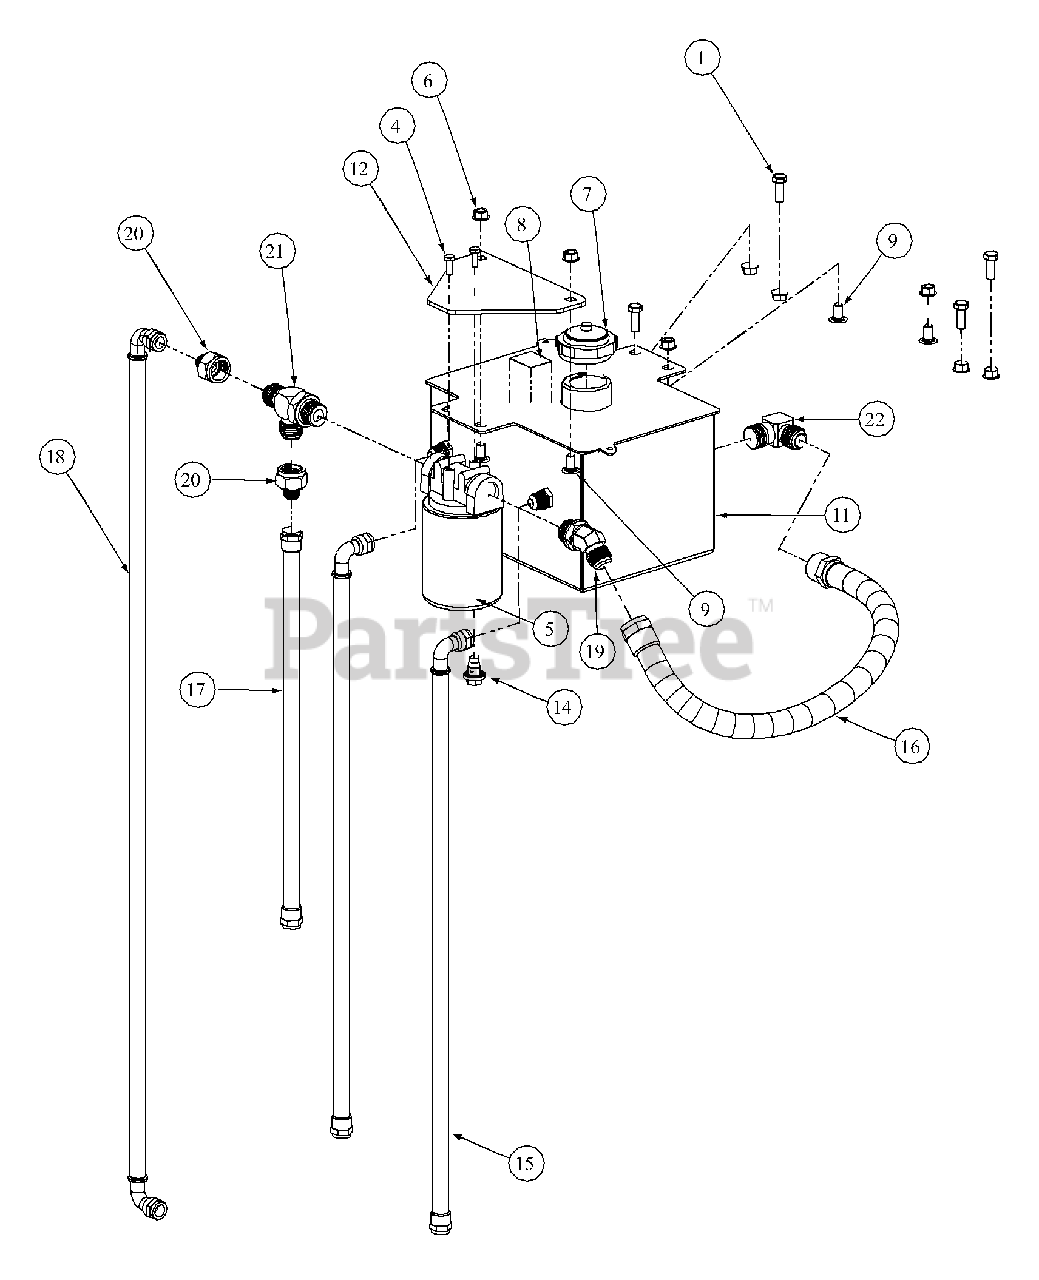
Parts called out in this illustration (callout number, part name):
1	Hex Cap Screw, 3/8-16, 1
4	Hex Cap Screw, 1/4-20, .75
5	Filter Head 3/4
6	Hex Nut Flange Lock, 3/8-16
7	Cap, Hydro Oil Tank
8	Decal Oil Only 20W50
9	Carriage Bolt, 3/8-16 x .75 LG.
11	Hydraulic Tank Assembly
12	Mounting Plate Oil Filter
14	Oil Pan Drain w/ Seal and Plug
15	Gearbox to Tank Hose Assembly
16	Tank to Filter Hose Assembly
17	Filter to LH Pump Hose Assembly
18	Filter to RH Pump Hose Assembly
19	Connector, 3/4 x3/4
20	Adapter 3/4 x 1/2
21	Fitting Tee, 3/4 x 3/4 x 3/4
22	Fitting Elbow, 1/2 x 1/2
